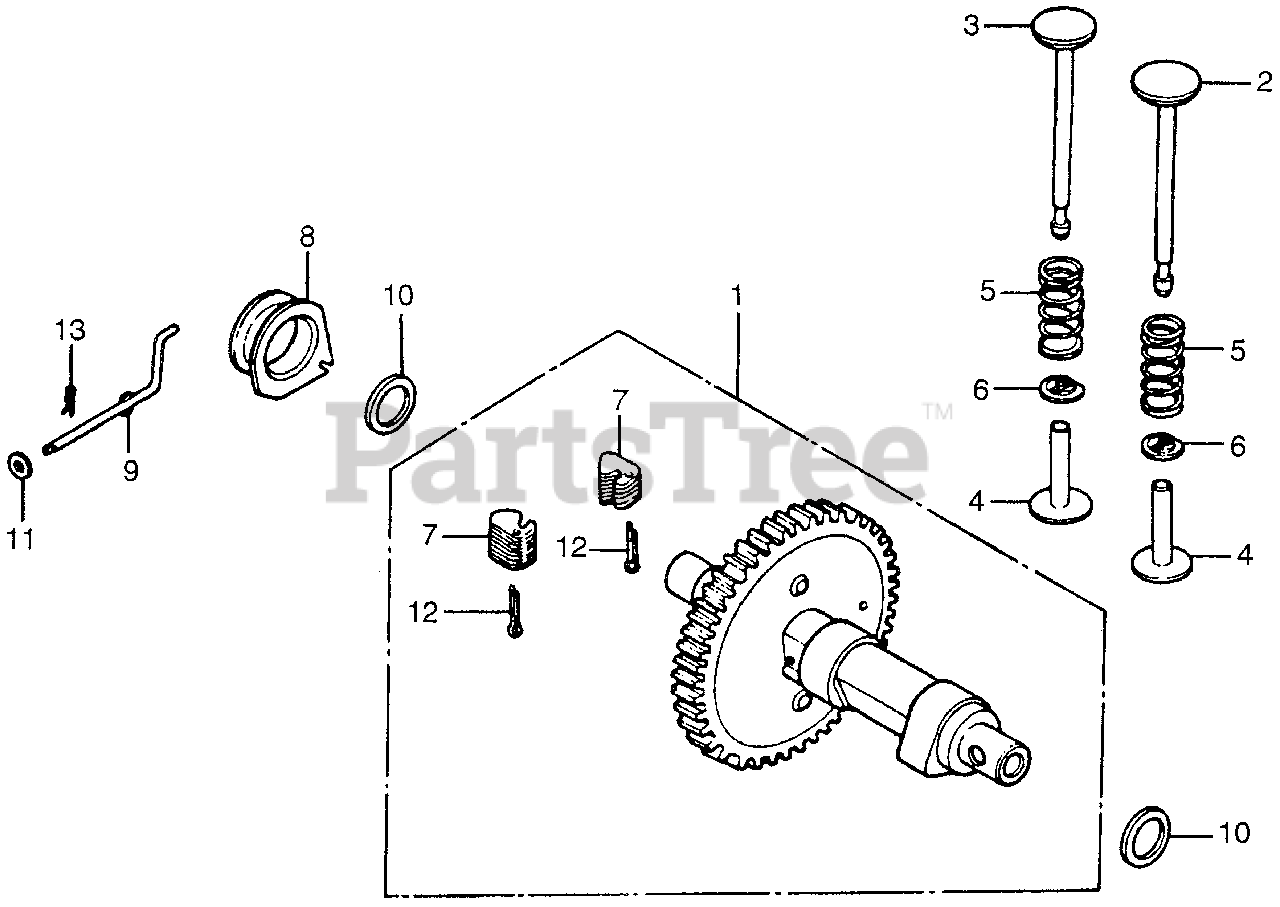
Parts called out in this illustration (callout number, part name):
1	CAMSHAFT ASSY.
2	VALVE, IN.
3	VALVE, EX.
4	LIFTER, VALVE (39.6MM)
4	LIFTER, VALVE (39.9MM)
5	SPRING, VALVE
6	RETAINER, VALVE SPRING
7	WEIGHT, GOVERNOR
8	SLIDER, GOVERNOR
9	SHAFT, GOVERNOR ARM
10	WASHER, THRUST (18MM)
11	WASHER, PLAIN (5MM)
12	PIN, COTTER (3.0X45)
13	PIN, LOCK (8MM)
